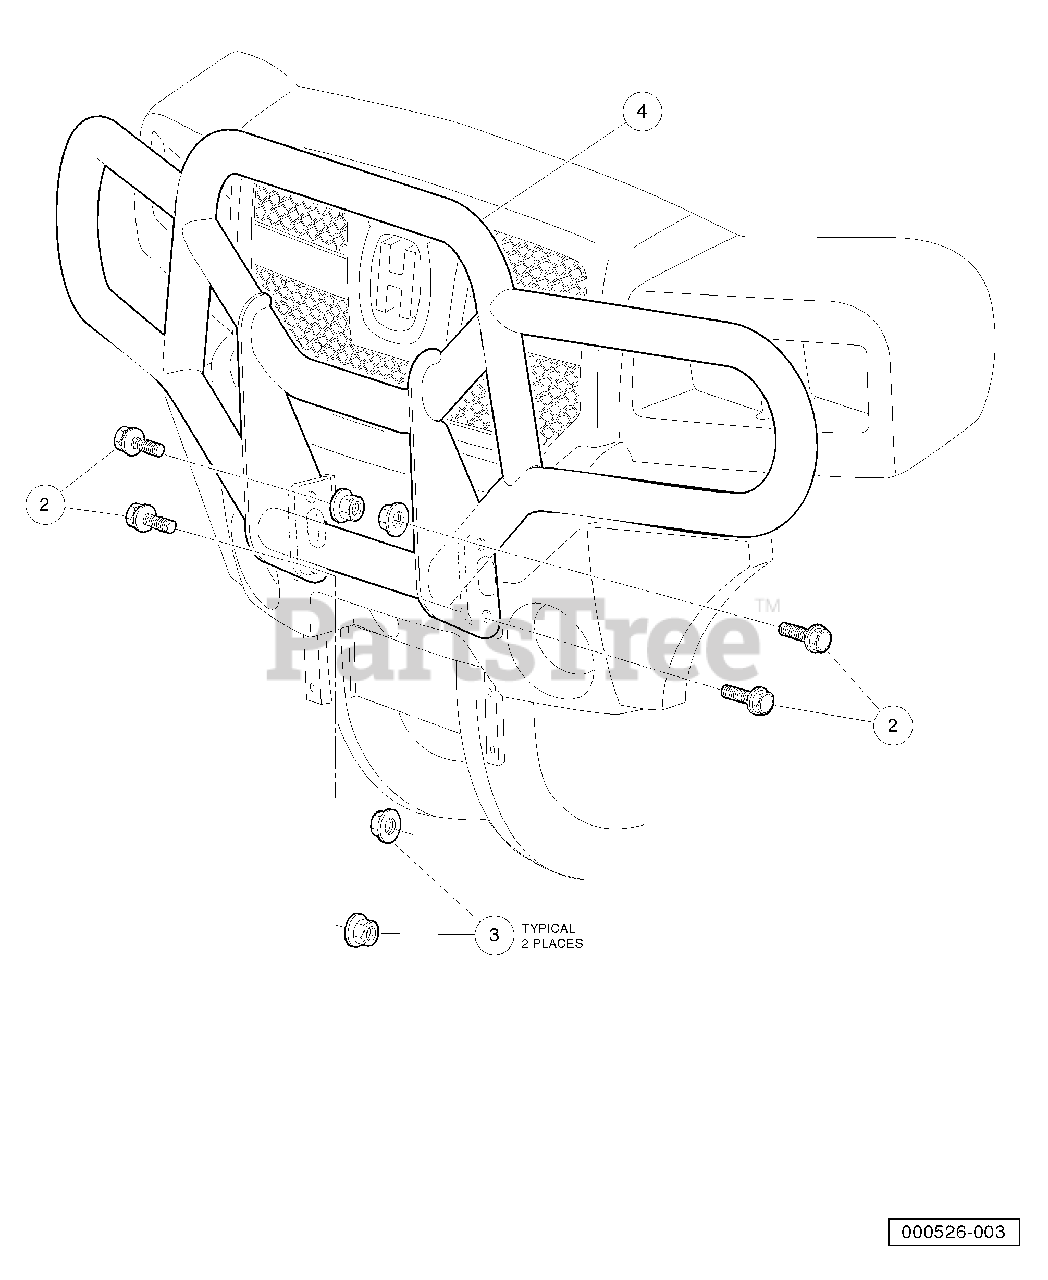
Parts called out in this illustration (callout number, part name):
1	Kit, Brush Guard Hus
2	Screw, M10 X 1.25 X 30 Hex Blk
3	Nut, Flg, M10 X 1.25 Hex Blk
4	Weldment, Brushguard, HUV 4421
